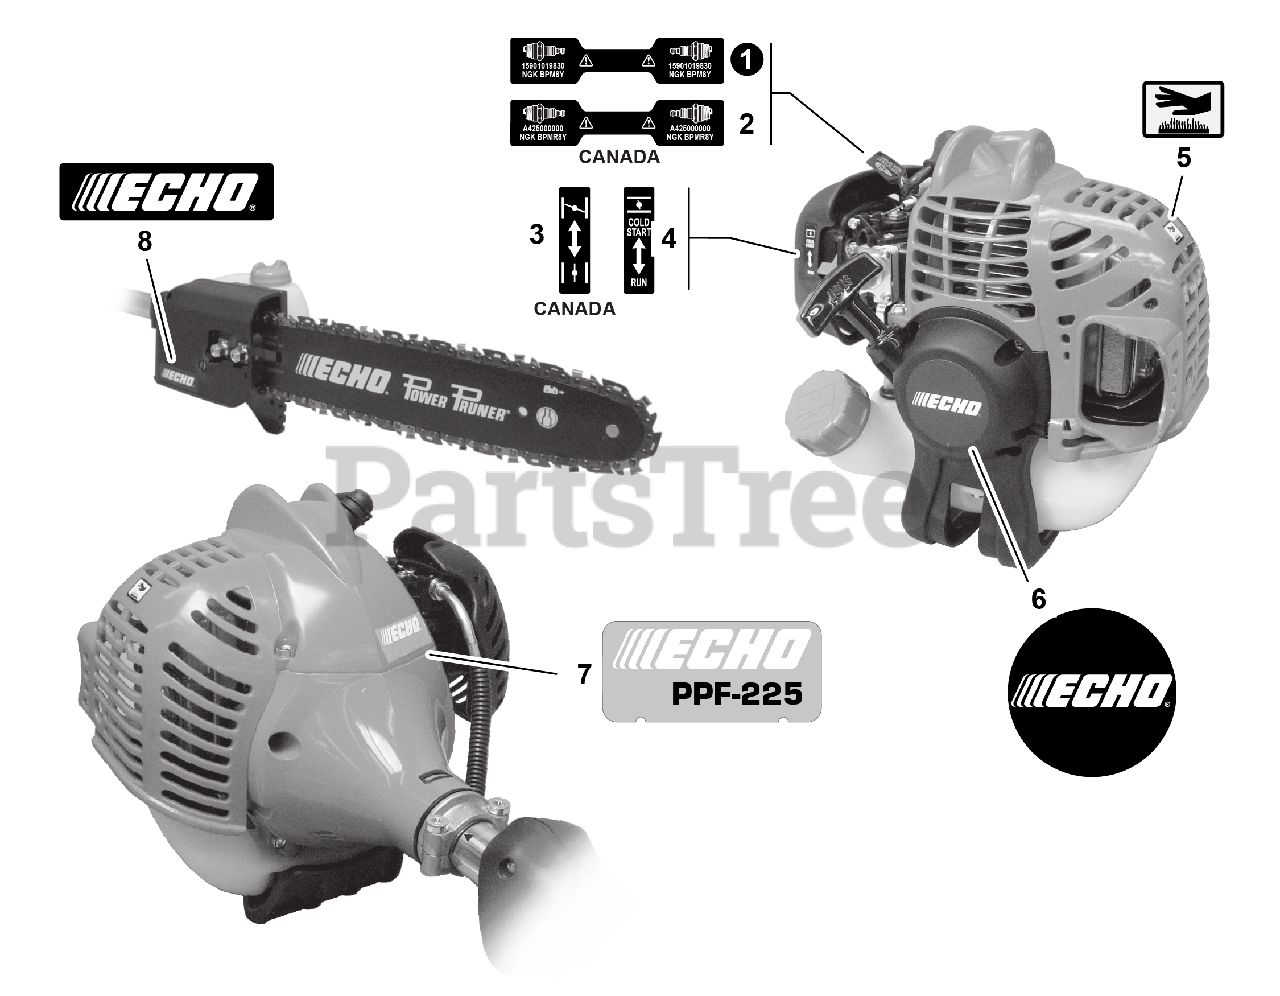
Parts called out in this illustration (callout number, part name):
1	LABEL, SPARK PLUG - BPM8Y
2	LABEL, SPARK PLUG - BPMR8Y
3	LABEL, CHOKE
4	LABEL, CHOKE
5	LABEL, CAUTION - HOT
6	LABEL, ECHO
7	LABEL, MODEL
8	LABEL, ECHO
